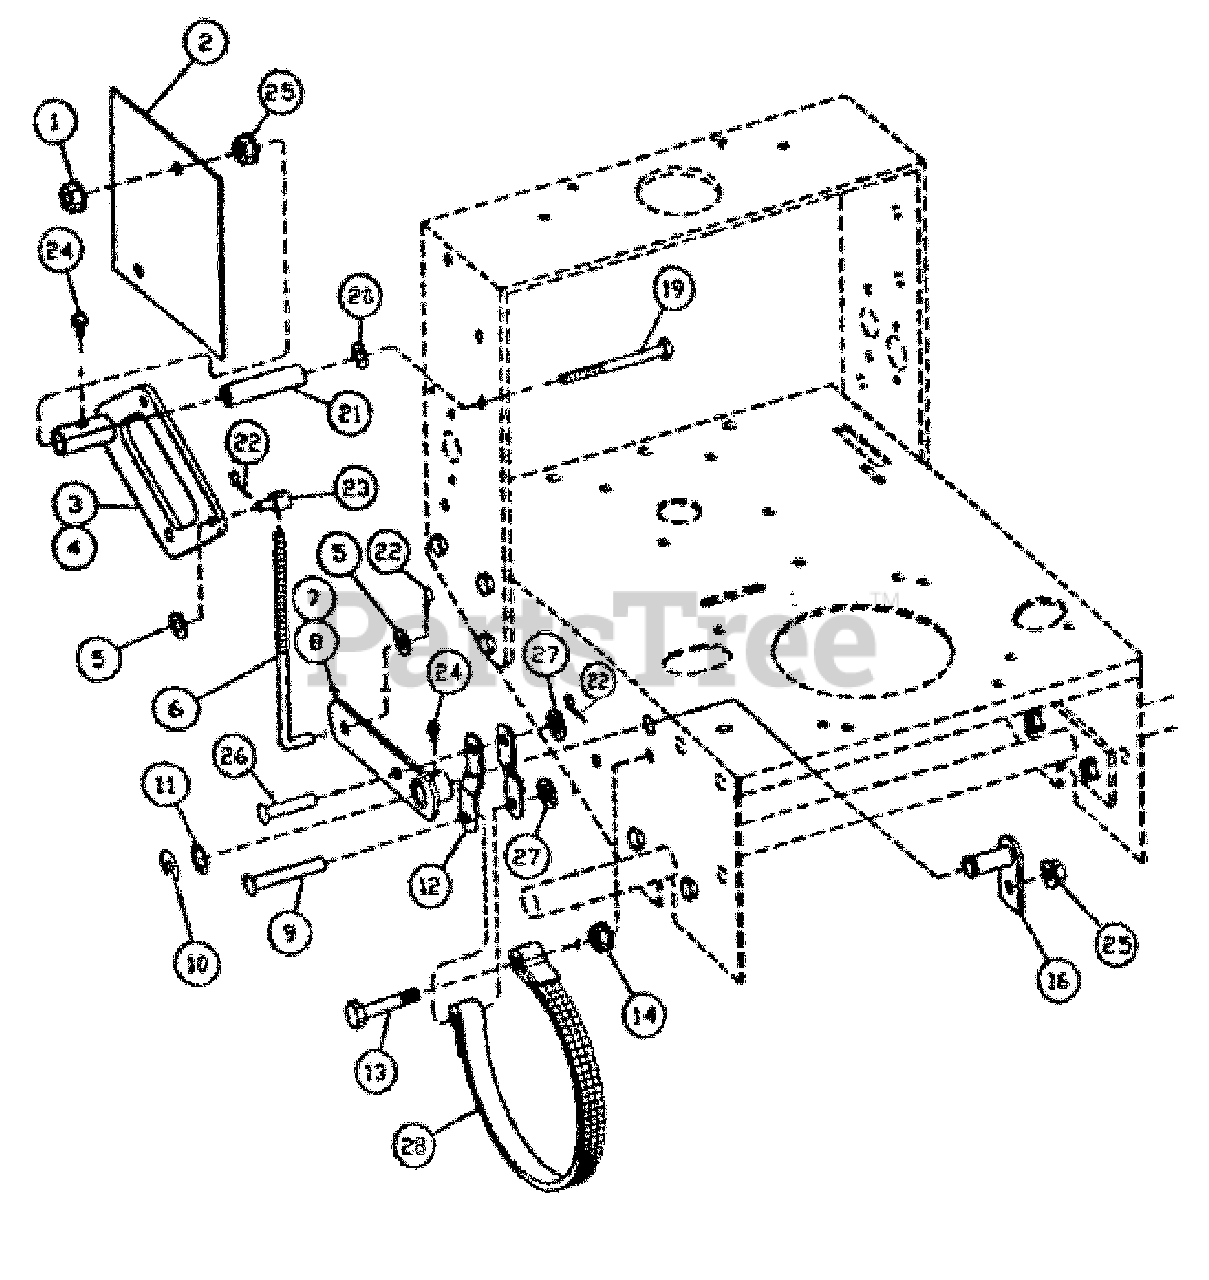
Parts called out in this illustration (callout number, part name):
1	NUT, 200-001 M10
2	100-005 FENDER
3	100-034 IDLER ARM RH
4	100-035 IDLER ARM LH
5	5/16STD FLAT WASHER.
6	100-036 BRAKE ROD
7	100-037 BRAKE LEVER RH
8	100-038 BRAKE LEVER LH
9	100-039 FLAT HEAD RIVET
10	200-047 SNAP-RING -10 PACK
11	100-120 PLAIN WASHER
12	100-040 BRAKE LINK
13	200-032 HEX BOLT M10`50
14	200-016 NUT FLANGE M10
16	100-041 BRAKE LVR MT.
19	200-008 HEX.BOLT M10`110
20	100-003 WASHER
21	100-004 PIVOT TUBE
22	200-014 COTTER PIN 2`20
23	100-042 SWIVEL BRAKE ROD
24	GREASE FTG (10 PACK) 200-026
25	200-006 NYLON NUT M10
26	100-043 FLAT HEAD RIVET
27	200-033 PLAIN WASHER 10
28	100-044 BRAKE ASM BAND
